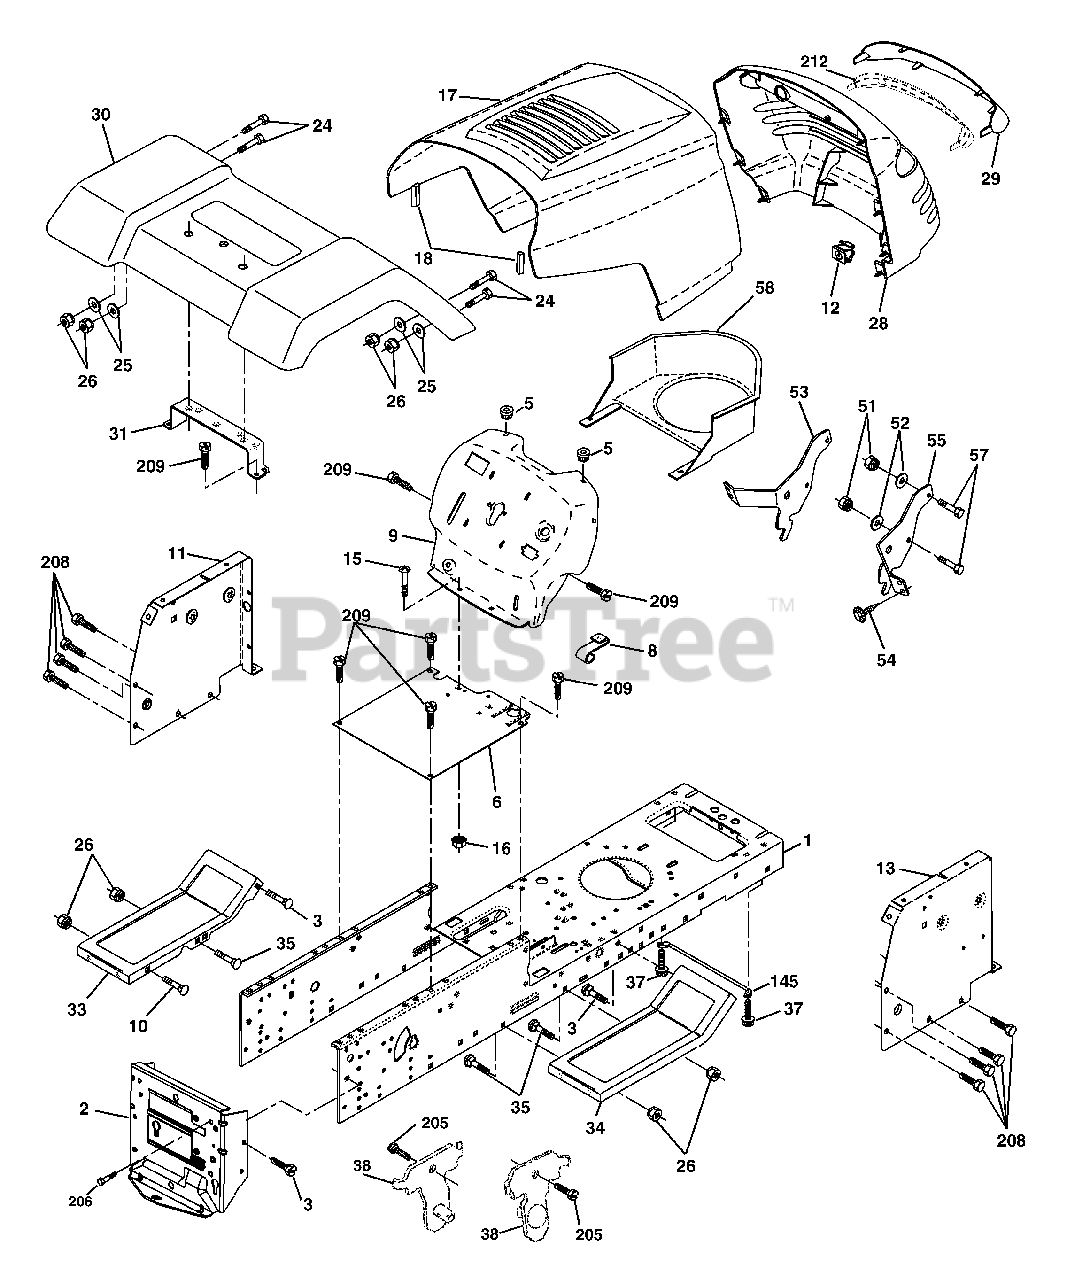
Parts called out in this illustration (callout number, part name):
1	Chassis
2	Drawbar, Stretch
3	Screw 3/8-16 x 3/4
5	Bumper, Hood/Dash
6	Saddle Silkscreen
8	Clip Retainer Slide-On
9	Dash
10	Bolt, Carriage 3/8-16 x 1
11	Panel Dash LH
12	Clip Tinnerman Grille P.L
13	Panel Slkscr Dash RH
15	Screw Mach TRHD 5/16-18uncx3/4
16	Nut Keps 5/16-18 Unc
17	Hood
18	Bumper Hood
24	Bolt Fin Hex 3/8-16unc X 1 Gr. 5
25	Washer 13/32 X 13/16 X 12 Ga
26	Nut Lock Hex w/Ins 3/8-16 Unc
28	Grille/Lens Asm.
29	Lens Grille Private Label
30	Fender
31	Bracket Fender Repl 109873x
33	Footrest Pnt LH
34	Footrest Pnt RH
35	Bolt Rdhd Sht Sqnk 3/8-16 X3/4
37	Screw Thdrol 5/16-18 x 1/2 TYT
38	Bracket Asm. Pivot Mower
51	Nut Lock W/Insert 1/4-20unc
52	Washer 9/32 x 7/8x16 Ga.
53	Bracket Grille Lh
54	Screw Hex 8-18 x 7/8
55	Bracket Grille Rh
57	Bolt Fin Hex 1/4-20 unc x .75
145	Rod Pivot Chassis/Hood
205	Screw Thdrol 3/8-16 x 1/2
206	Bolt Shoulder 5/16-18
208	Screw Thdrol 3/8-16 x 1/2
209	Screw Hex Wsh Thdrol 3/8-16
212	Insert Lens Reflect
